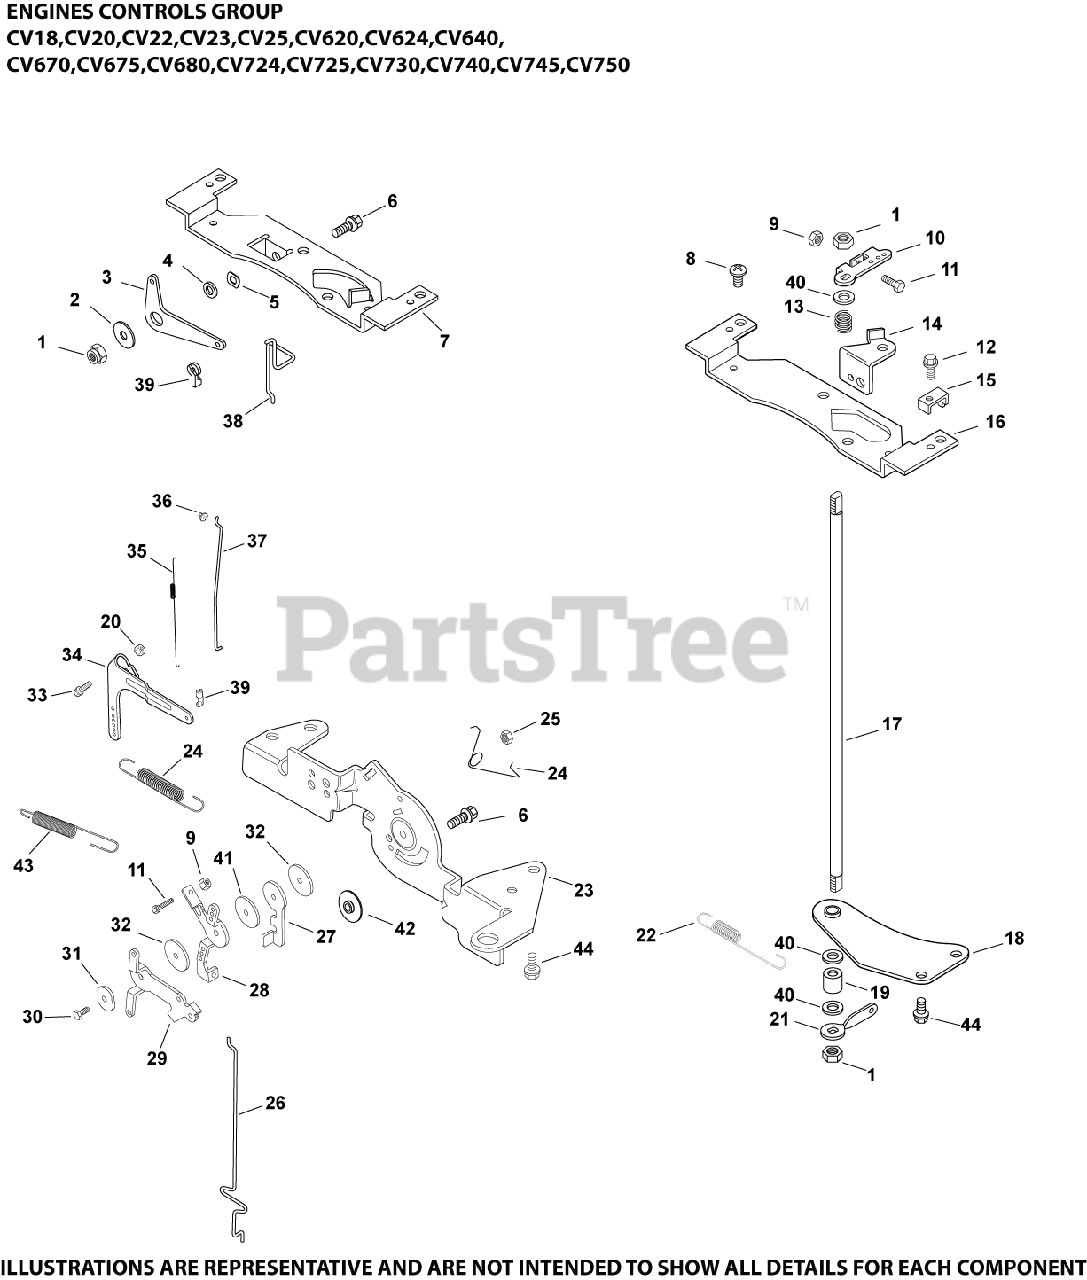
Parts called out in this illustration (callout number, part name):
1	NUT, LOCK M6X1.0
2	WASHER, FLAT 1/4"
3	LEVER, CHOKE
5	WASHER, SPRING 3/8"
6	SCREW, FLG M6X1.0X16
7	BRACKET, CONTROL
9	NUT, M4X0.7
10	LEVER, THROTTLE CONTROL
11	SCREW, CAP M4X.7X30
17	SHAFT, THROTTLE
18	BRACKET, THROTTLE SHAFT
20	NUT, FLG M6X1.0
21	LEVER, THROTTLE CONTROL
22	SPRING, GOVERNOR (BLUE)
22	SPRING, GOVERNOR (ORANGE)
22	SPRING, GOVERNOR (GREEN)
23	BRACKET, CONTROL-USE 24 126 176-S
23	BRACKET, CONTROL
23	BRACKET, CONTROL-USE 24 126 172-S
23	BRACKET, CONTROL - (#3212604S)
24	SPRING, CHOKE RETURN
25	NUT, LOCK M5X.8
26	LINKAGE, CHOKE
27	LEVER,THROTTLE ACTUATOR-USE(24 090 65-S
27	LEVER, THROTTLE ACTUATOR
28	LEVER, THROTTLE CONTROL
29	LEVER, CHOKE
30	SCREW, FLG THD FRM M5X.8X20-(#25086399S)
30	SCREW, THREAD FORMING - USE 25 086 473-S
31	WASHER, SPRING 1/4"
33	BOLT, RD HD SQ NECK M6X1.0X25
34	LEVER, GOVERNOR ASSEMBLY
35	SPRING, LINKAGE
36	BUSHING, LINKAGE RETAINING
37	LINKAGE, THROTTLE
38	LINKAGE, CHOKE
39	BUSHING, THROTTLE LINKAGE
40	WASHER, FLAT 1/4"
